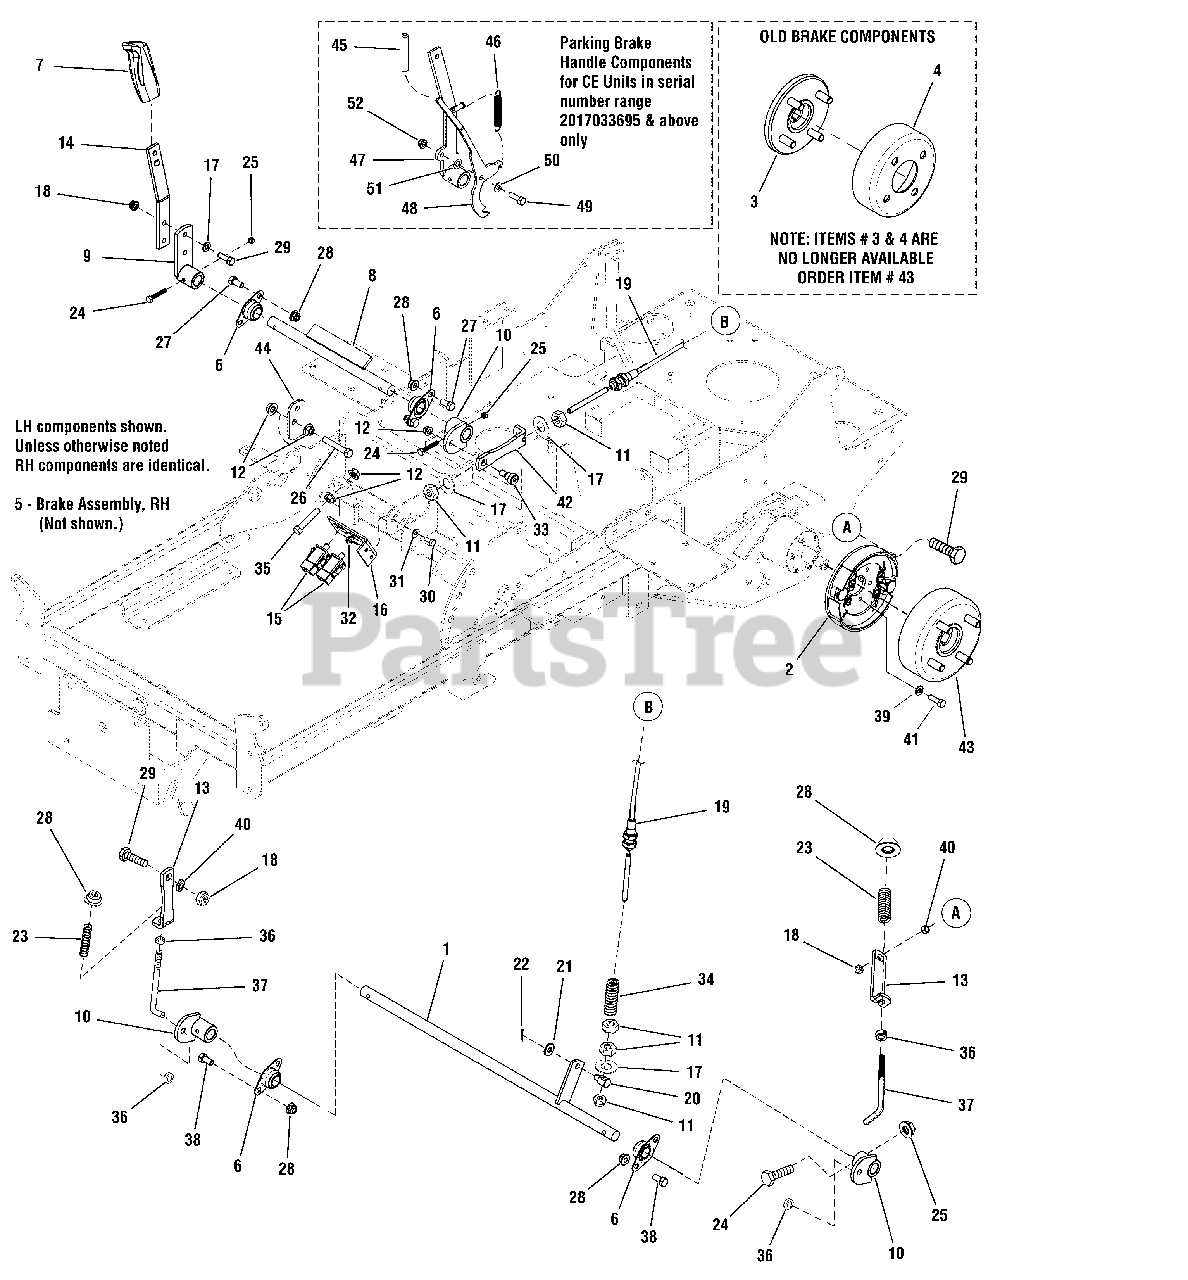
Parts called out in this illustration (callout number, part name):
1	WELD, SHAFT, REAR BRAKE
2	BRAKE SHOE ASM, LH, KNOTT
3	HUB W/ STUDS, 1" TAPER
4	BRAKE DRUM, 4 BOLT, KNOTT
6	BEARING, BRONZE FLANGE, 3/4
7	GRIP, BLACK FLEXIBLE
8	WELD,SHAFT,BRAKE LEVER
9	WELD,MOUNT,BRAKE LEVER - ORG
10	PIVOT, LINKAGE MOUNT WELDMENT
11	NUT, 5/16-24 HEX
12	NUT, 3/8-16 HEX SERRATED FLANGE
13	LINK, BRAKE LOCK - ORG
14	HANDLE, BRAKE LEVER - ORG
15	SWITCH, DP NO/NC SNAP-IN
16	BRACKET, SWITCH MOUNT
17	WASHER, 5/16" SAE
18	NUT, 5/16-18 HEX NYLOCK FLANGE
19	* CABLE, PARKING BRAKE
20	ADJUSTER, BRAKE LINKAGE
21	WASHER, 5/16 USS
22	PIN, COTTER, 3/32" X 3/4
23	SPRING, BRAKE
24	BOLT, 1/4-20 X 1-1/2", GD5
25	NUT, 1/4-20 HEX SIDE LOCK
26	BOLT, 3/8-16 X 2-1/4" GD5
27	BOLT, 3/8-16 X 3/4" GD5 YZ
28	NUT, 3/8-16 HEX NYLOCK FLANGE
29	BOLT, 5/16-18 X 1" GD5 YZ
30	BOLT,1/4-20X5/8
31	WASHER, 1/4 SAE (5025154)
32	NUT, 1/4-20 HEX SERR. FLANGE
33	BOLT, 3/8-16 X 3/8", 1/2" SHOULDER
34	SPRING, COMPRESSION, 5-1/2
35	BOLT, 3/8-16 X 2" GD5 TFL CZ
36	COLLAR, 3/8" SET
37	ROD, BRAKE ADJUSTMENT
38	BOLT, 3/8-16 X 1" GD5 YZ
39	WASHER, 1/4" LOCK
40	SPACER, .38 X .50 X.27
41	CAPSCREW,HEX HEAD M6-1.0X 14MM
42	LINK, BRAKE LOCK
43	BRAKE DRUM, 4-BOLT
44	PLATE, SUPPORT, FRAME, CONZ - EU - ORG
45	COVER, VINYL HANDLE
46	SPRING-EXT, .500 OD X 3.50 LG X .058 WR
47	WELD, HANDLE, BRAKE, CONZ - EU - ORG
48	LEVER, BRAKE, CONZ - EU - ORG
49	BOLT, 5/16-18 X 1 GD5 CZ
50	WASHER, 5/16 SAE
51	WASHER, WAVE, M10
52	NUT, 5/16-18 HEX NYLOCK FLANGE
